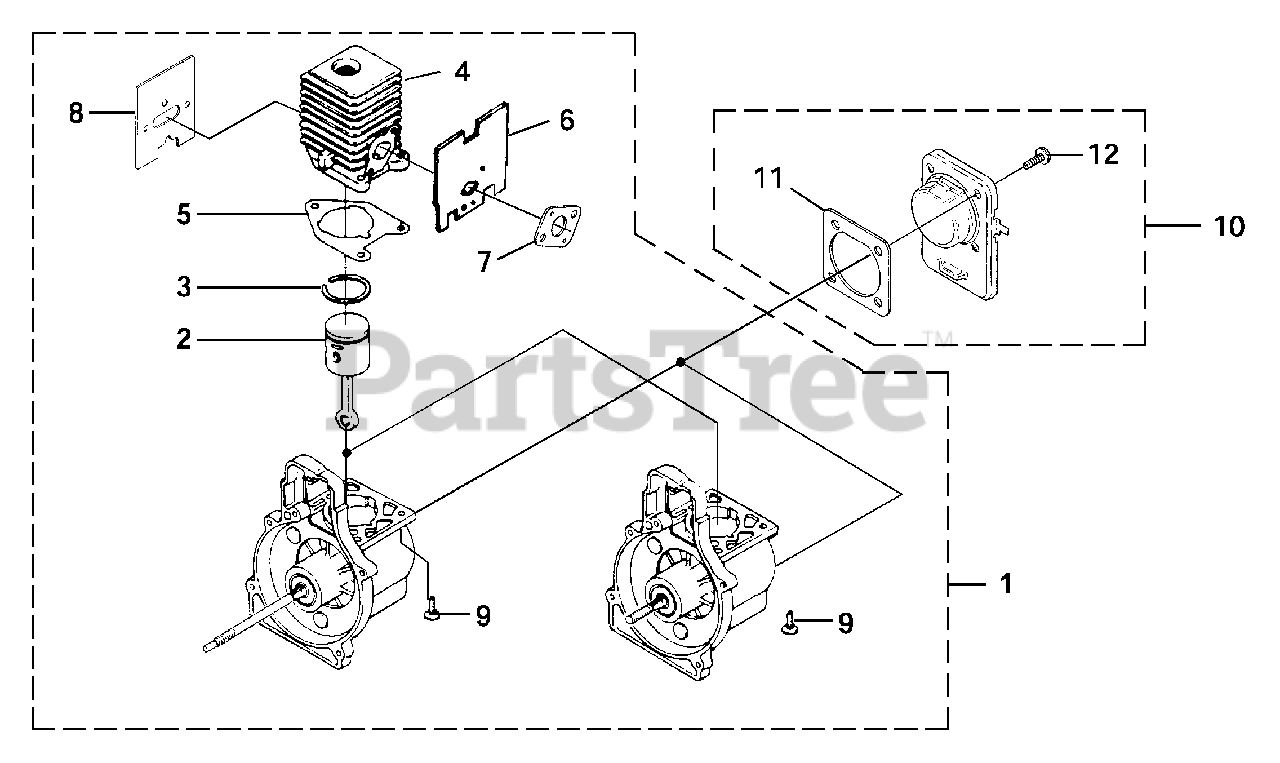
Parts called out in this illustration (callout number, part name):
1	SHORT BLOCK (Non-Clutch)
2	PISTON & ROD ASSY.
3	RING-Piston
4	CYLINDER ASSY.
5	GASKET-Cylinder
6	GASKET-Heat Dam
7	GASKET-Carburetor
8	GASKET-Muffler
9	SCREW-Sems (12-24 X 3/4")
10	CRANKCASE COVER ASSEMBLY
11	GASKET-Crankcase Cover
12	SCREW-Sems (10-24 X 1/2")
